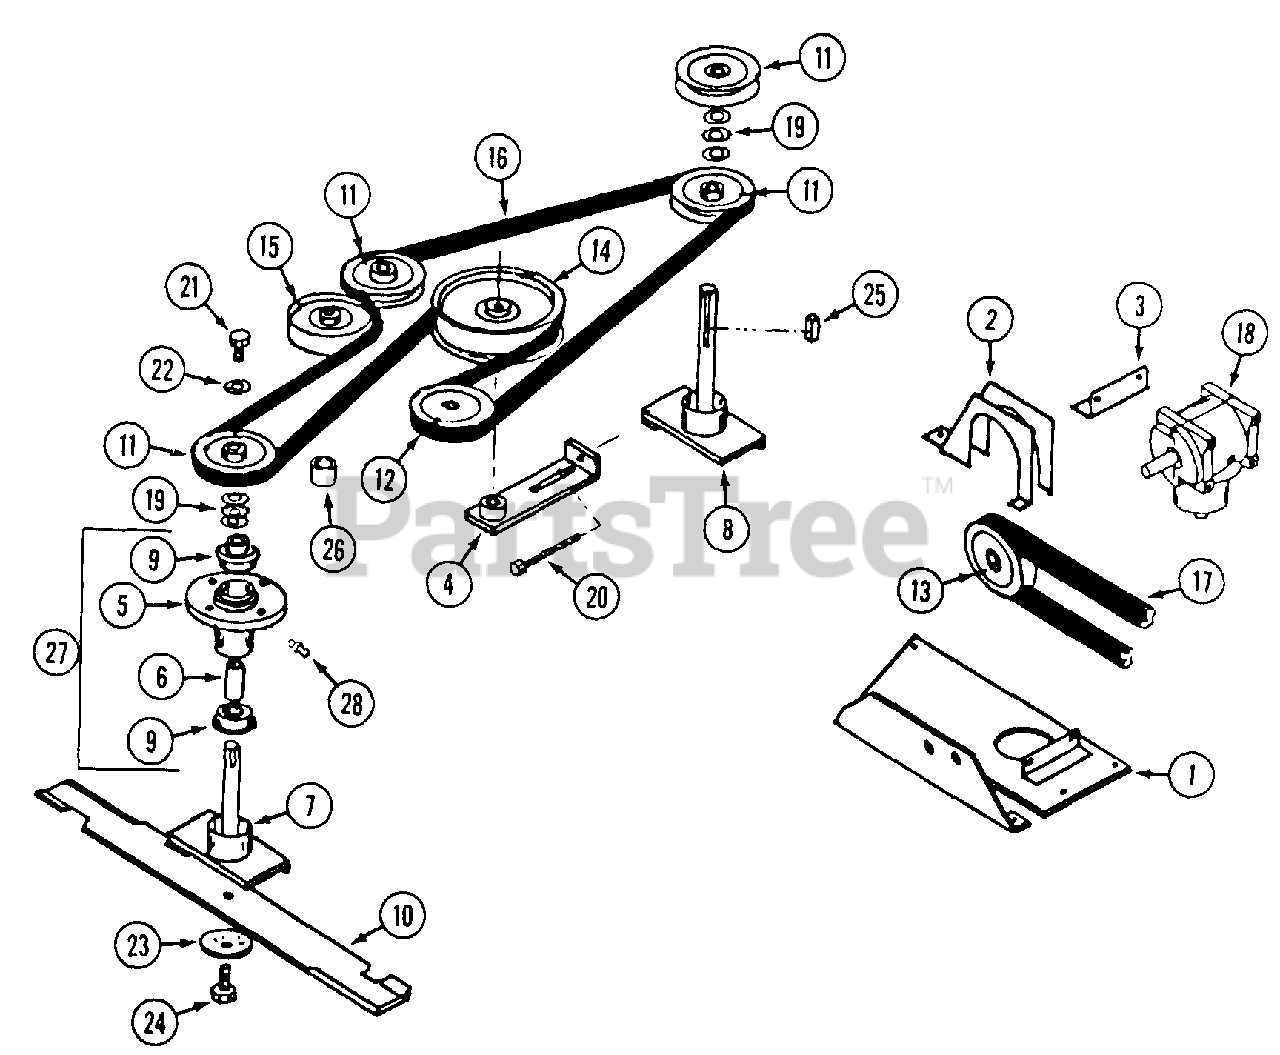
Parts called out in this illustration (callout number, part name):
1	MOUNT - gear box
2	GUARD - belt
3	ANGLE - gear box mount
4	TIGHTENER - belt
5	HOUSING - spindle
6	SPACER - spindle
7	SHAFT - spindle, short
8	SHAFT - spindle, long
9	BEARING - spindle
11	PULLEY - spindle
12	PULLEY - gear box output
13	PULLEY - gear box input
14	PULLEY - idler, large
15	PULLEY - idler, small
17	BELT - drive
18	GEAR BOX - angle drive
19	WASHER - spacer
20	BOLT - 1/4"-20 x 4"
21	BOLT - 5/16"-24 x 3/4"
22	WASHER - 5/16", 10 ga
23	WASHER - blade
24	BOLT - 3/8"-24 x 1-1/4"
25	KEY - 3/16" x 3/16" x 1"
26	SPACER - idler pulley
27	HOUSING ASSEMBLY - spindle
28	FITTING - grease 1/4"-28
